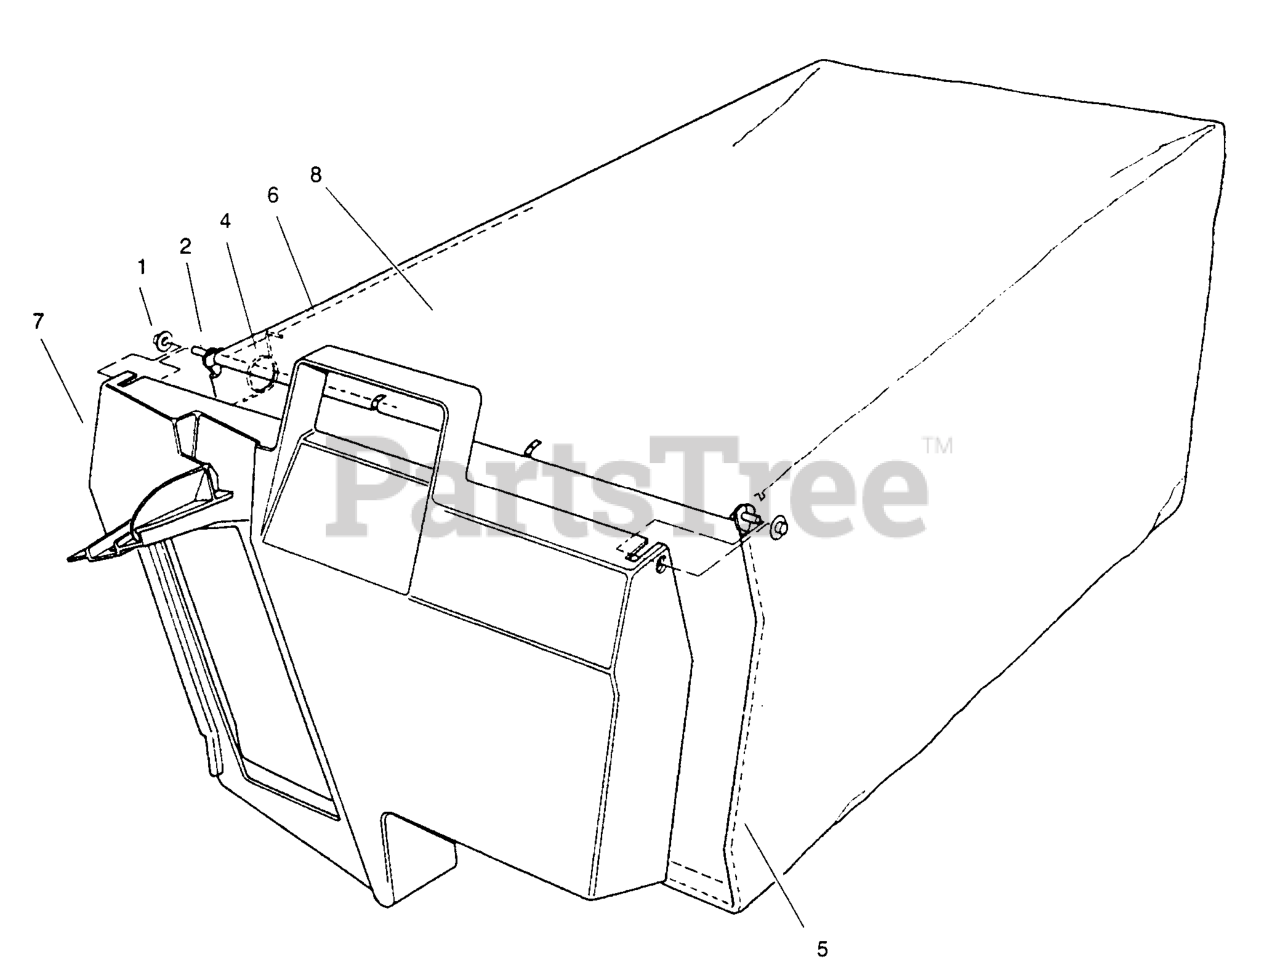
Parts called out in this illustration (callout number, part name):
1	NUT-PUSH
2	HINGE-DOOR, BAG
5	FRAME-BAG
